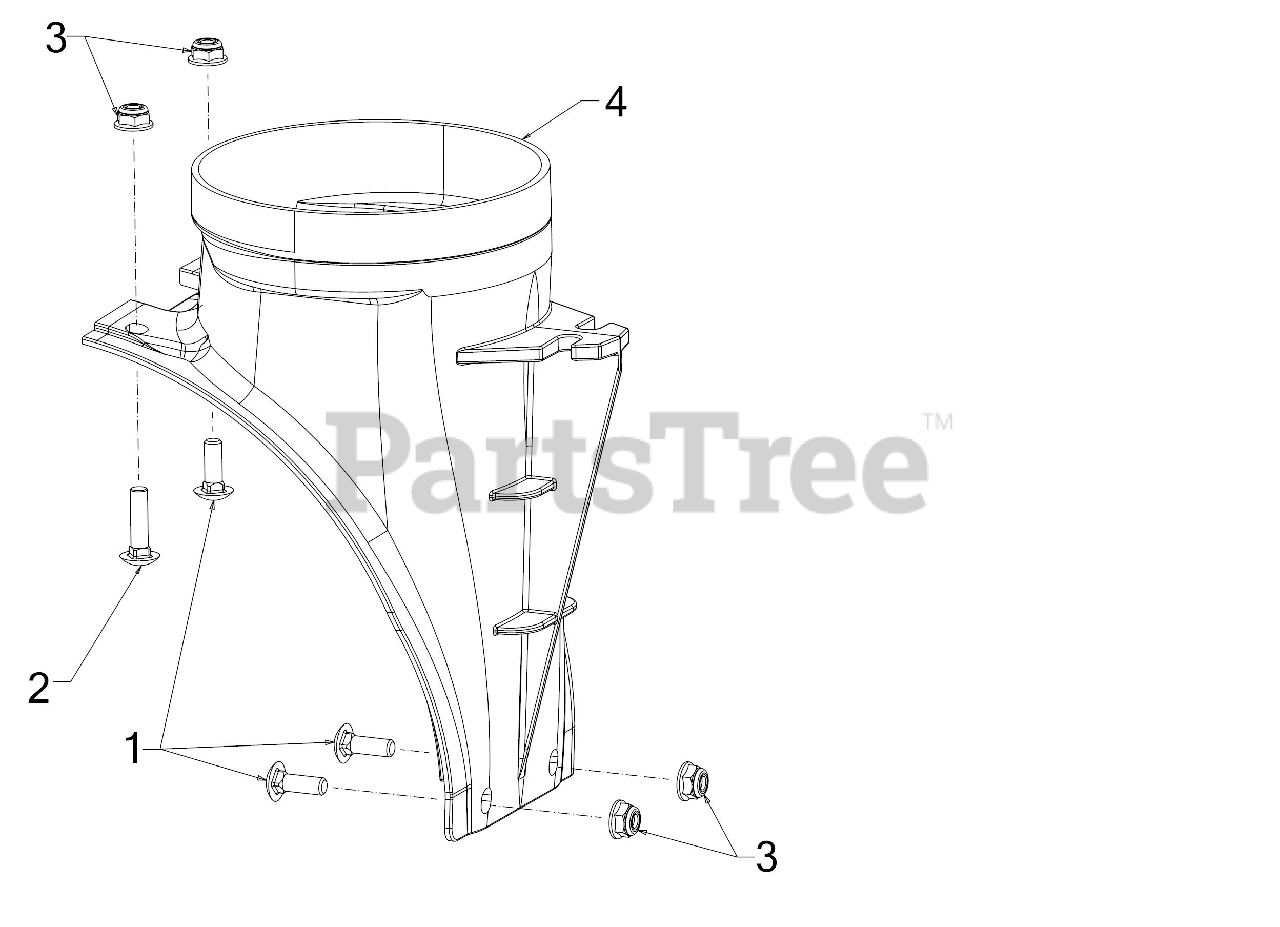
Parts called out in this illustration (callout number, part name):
1	SCREW 1/4-20 x .75 GR5
2	SCREW 1/4-20 x 1 GR5
3	FLANGE LOCK NUT
4	CHUTE ADAPTER 5"
